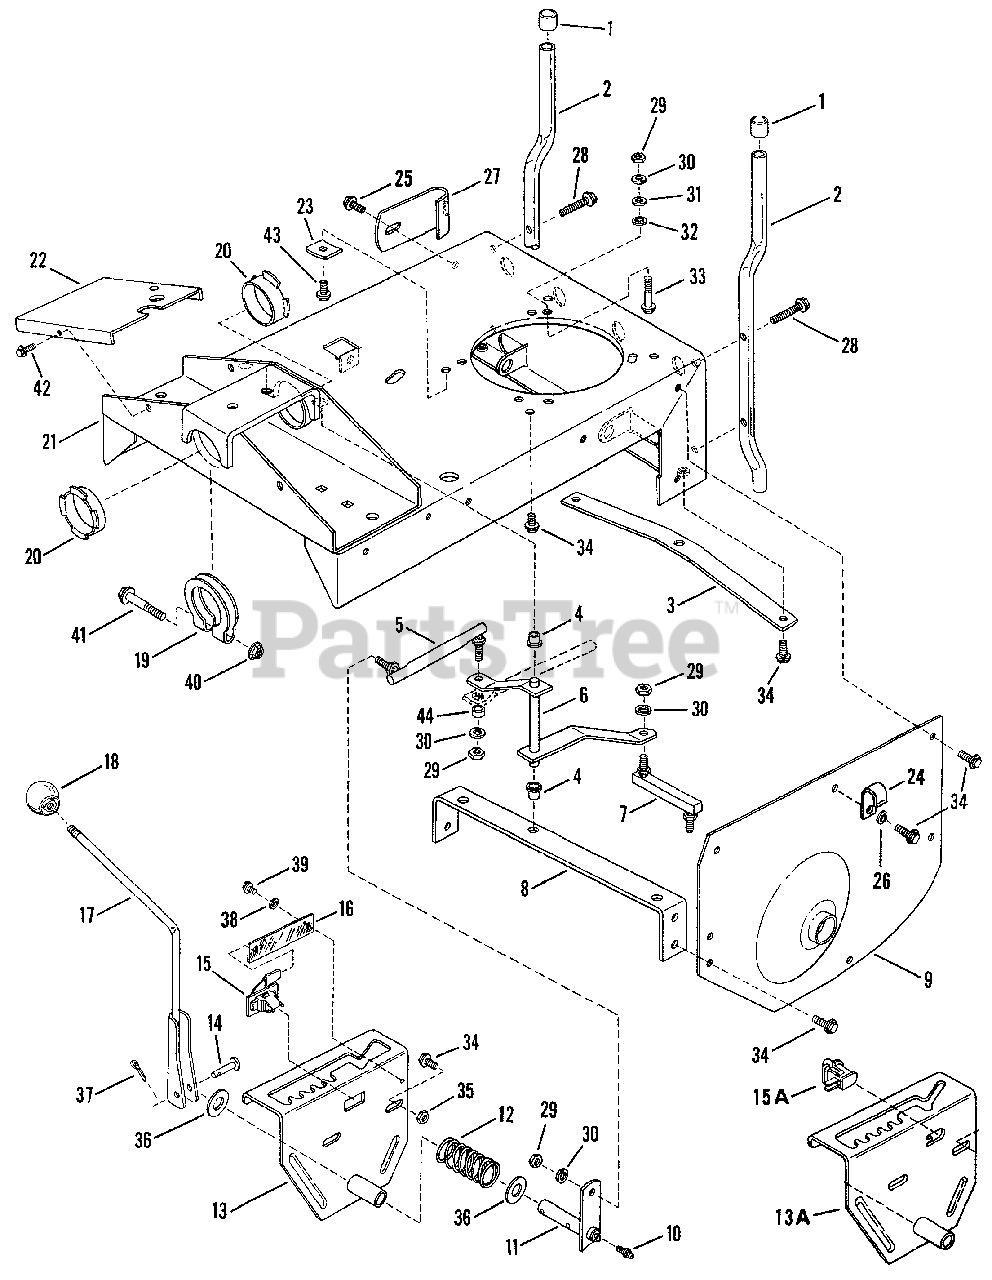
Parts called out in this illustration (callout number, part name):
1	CAP, Bumper
2	BUMPER, Rear
3	PLATE, Hitch
4	BUSHING, Nylon
5	LINK, Shift, Long
6	ARM, Shift
7	LINK, Shift, Short
8	BRACE, Cross
9	FENDER, Left Hand
10	FITTING, Lube (Press fit for .187 hole-no ball)
11	ARM, Shift Handle
12	SPRING, Shift Handle
13	DETENT, Shift
13A	DETENT, Shift
14	CLEVIS-PIN, 3/8x1-1/4"
15	SWITCH, Interlock, Assembly
15A	SWITCH, Seat
16	PROTECTOR, Switch
17	HANDLE, Shift
18	KNOB, Shifter Ball
19	CLAMP, Main Tube
20	GROMMET, Main Tube
21	MAIN-CASE,
22	PANEL, Switch
23	WASHER, Clip
24	CLIP, Wire
25	SCREW, 5/16-18x3/4" Self-Tapping
26	WASHER, 5/16 Internal Tooth Lock
27	SUPPORT, Bumper
28	SCREW, 5/16-18x1 1/2", Self-Tapping
29	NUT, 5/16-24 Hex
30	LOCKWASHER, 5/16 Split Lock
31	WASHER, 5/16 Flat
32	RETAINER, Bolt
33	SCREW, 5/16-24x1-1/2" Hex Cap
34	SCREW, 5/16-18x5/8", Self-Tapping
35	NUT, 5/16-18 Hex
36	WASHER, Thrust
37	PIN, 3/32x3/4", Cotter
38	WASHER, #10 Flat
39	SCREW, #10-24 x 1/2" Hex Washer Self-Tap (Torx)
40	NUT, 5/16-24 Hex Flange Lock
41	SCREW, 5/16-24x2-1/2" Hex Cap
42	SCREW, 1/4-20x1/2" Self-Tapping
43	SCREW, 3/8-16x1" Self-Tapping
44	ROLLER
